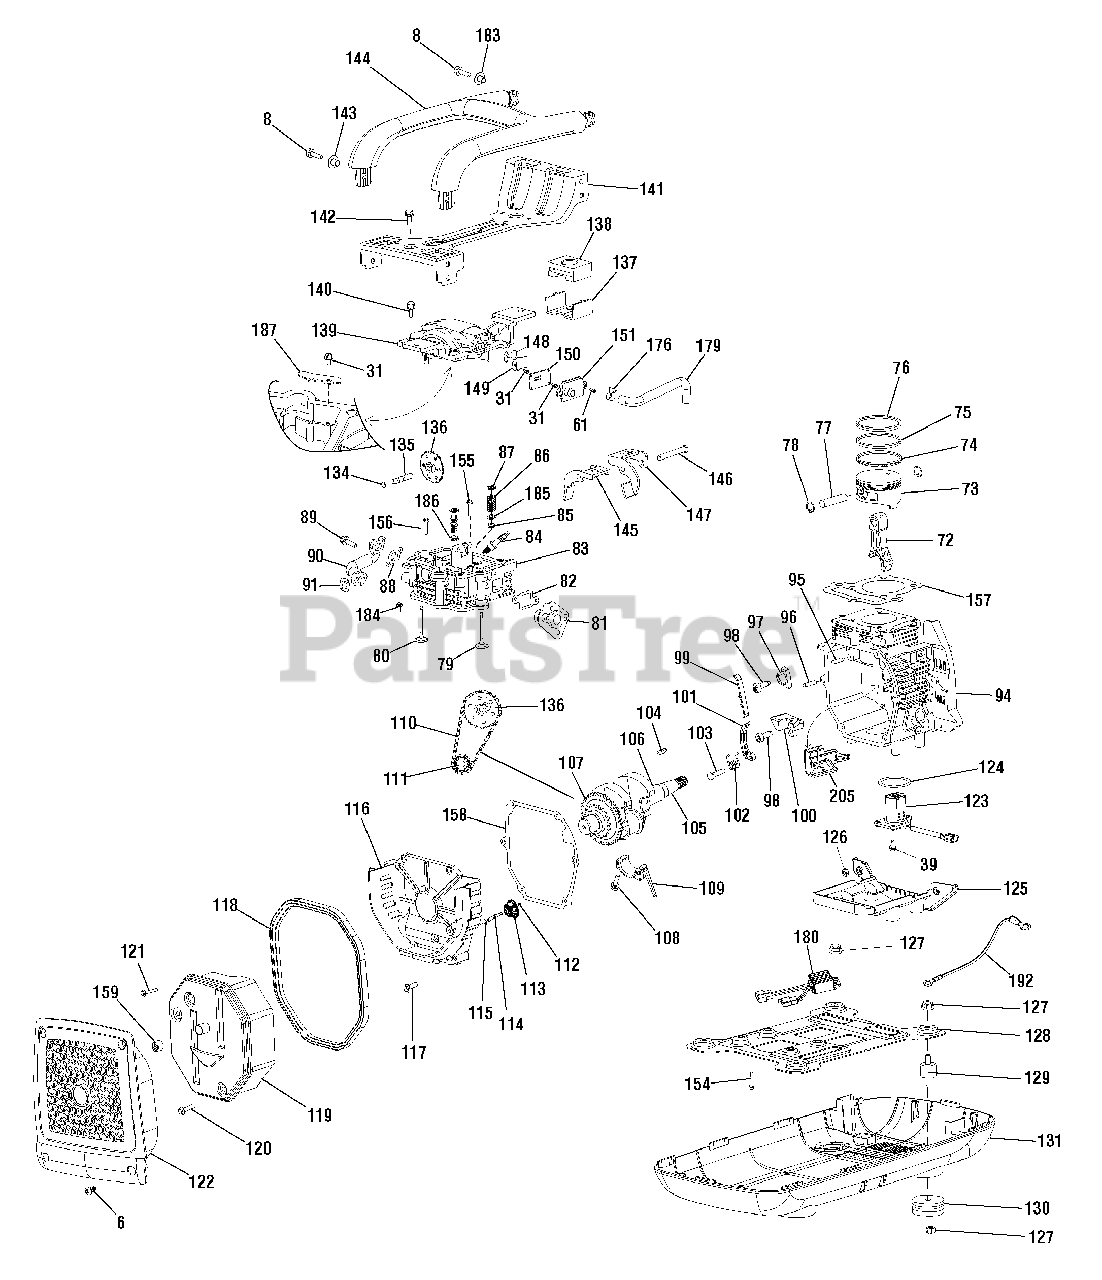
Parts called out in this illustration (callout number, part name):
31	BOLT
61	SCREW
72	ROD
73	PISTON
74	RING
75	RING
76	RING
77	PIN
78	RETAINER-PIN
79	VALVE-INTAKE
80	VALVE-EXHAUST
83	CYLINDER HEAD
85	SEAL-VALVE OIL
86	SPRING
87	SEAT-VALVE
89	BOLT
90	MUFFLER
94	CRANKCASE
95	PIN
96	PIN
97	BLOCK
98	SCREW
99	BRACKET
100	BRACKET
101	ARM-TENSION
102	SPRING
103	PIN
104	KEY
105	CRANKSHAFT
106	BEARING
107	GEAR
108	BOLT
109	COVER
110	CHAIN
111	WHEEL-CHAIN
112	SPRING
113	WHEEL-OIL
114	SHAFT
115	SHIM
116	COVER-CRANKCASE
117	BOLT
118	BLOCK-RUBBER
119	MUFFLER
120	BOLT
121	BOLT
124	O-RING, 33.5 x 2.65
125	COVER
126	NUT
127	NUT
129	MOUNT-VIBRATION
130	MOUNT-VIBRATION
134	O-RING
135	SHAFT
136	CAM-ASSEMBLY
137	BRACKET
138	MOUNT-VIBRATION
140	BOLT
141	BRACKET
142	BOLT
145	ARM-EXHAUST VALVE
146	PIN
147	ARM-INTAKE VALVE
150	BOARD-VALVE
151	BOARD-VALVE
154	BOLT
155	BOLT
156	BOLT
157	GASKET
158	GASKET-CRANKCASE
176	CLAMP
180	REGULATOR-VOLTAGE
184	BOLT
185	SEAT
186	SEAT
187	PLATE
205	BREATHER
